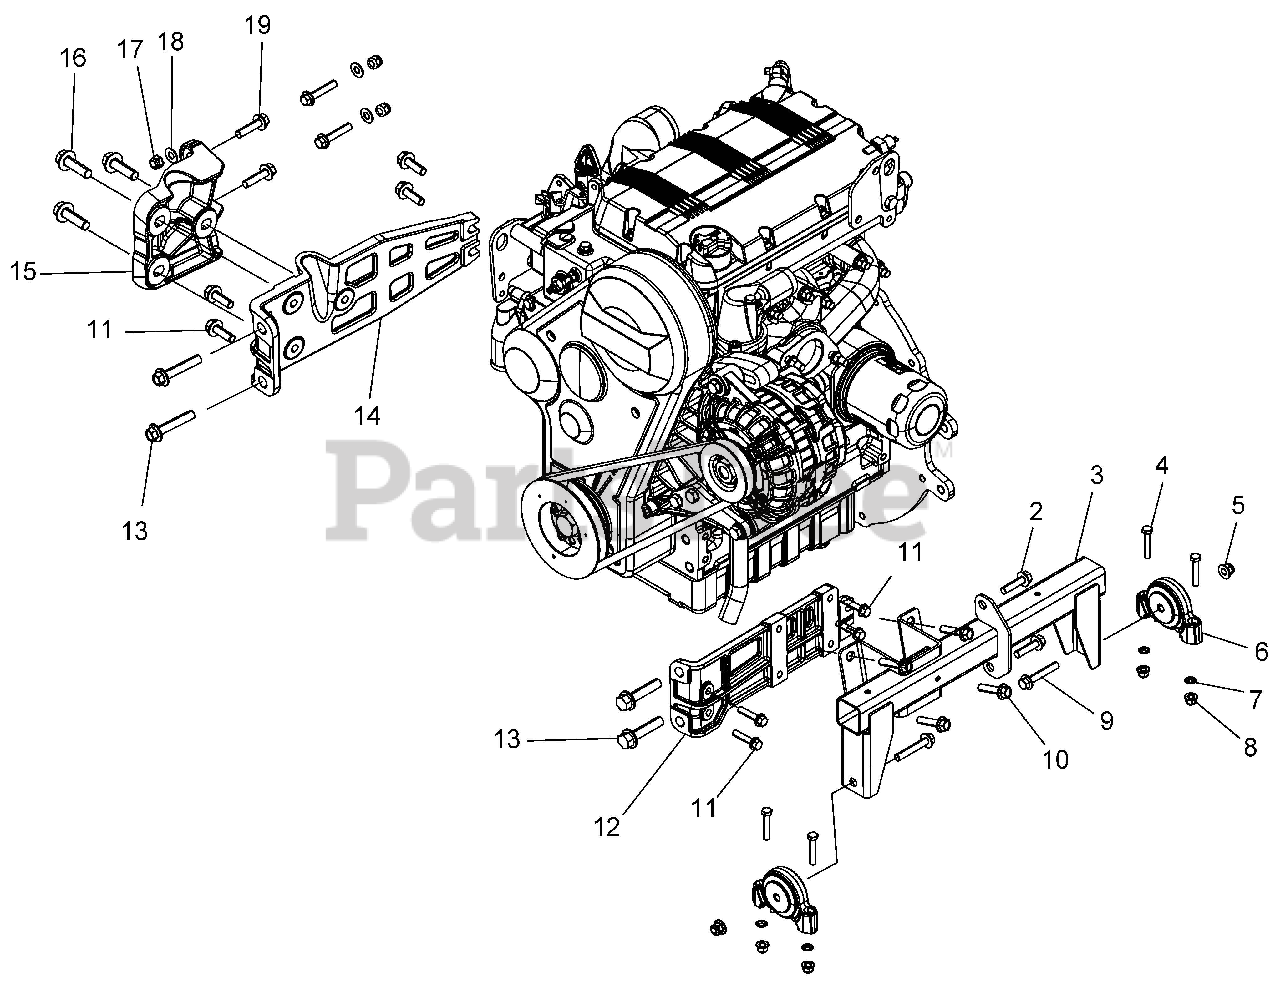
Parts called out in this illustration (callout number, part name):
1	ASM., ENGINE, KDW1003T
3	MOUNT, ENGINE
6	MOUNT, ISOLATOR, DRIVELINE
7	NUT, PAL
12	COUPLER, L, ENGINE, FRONT
14	COUPLER, ENGINE, GEARCASE
15	COUPLER, L, ENGINE, GEARCASE
